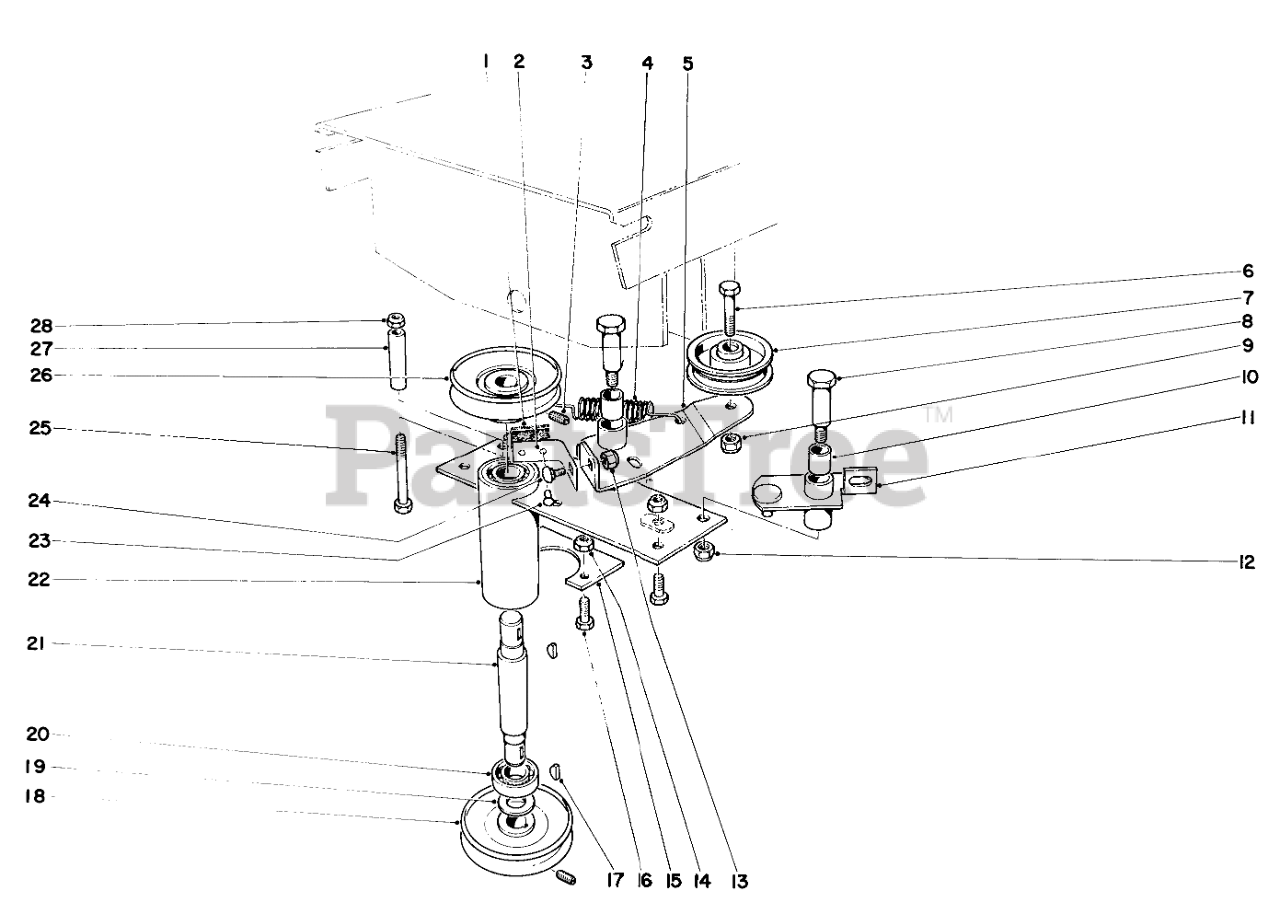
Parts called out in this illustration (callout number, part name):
1	BLADE BRAKE LINING
2	Brake Spring
3	SCREW-SET
4	Spring
5	Idler Plate
6	SCREW-HH
7	Pulley
8	Shoulder Bolt
10	Bushing
11	Pivot Bracket Incl. Ref. #10
14	Nut
15	Retainer Power Take Off Tube
16	SCREW-HH
17	KEY-WOODRUFF
18	Pulley
19	Bearing Washer
20	Bearing
21	Shaft
22	Power Take Off Tube
23	Rivet
24	SCREW-CARR
25	SCREW-HH
26	Pulley
27	Spacer
28	Nut
